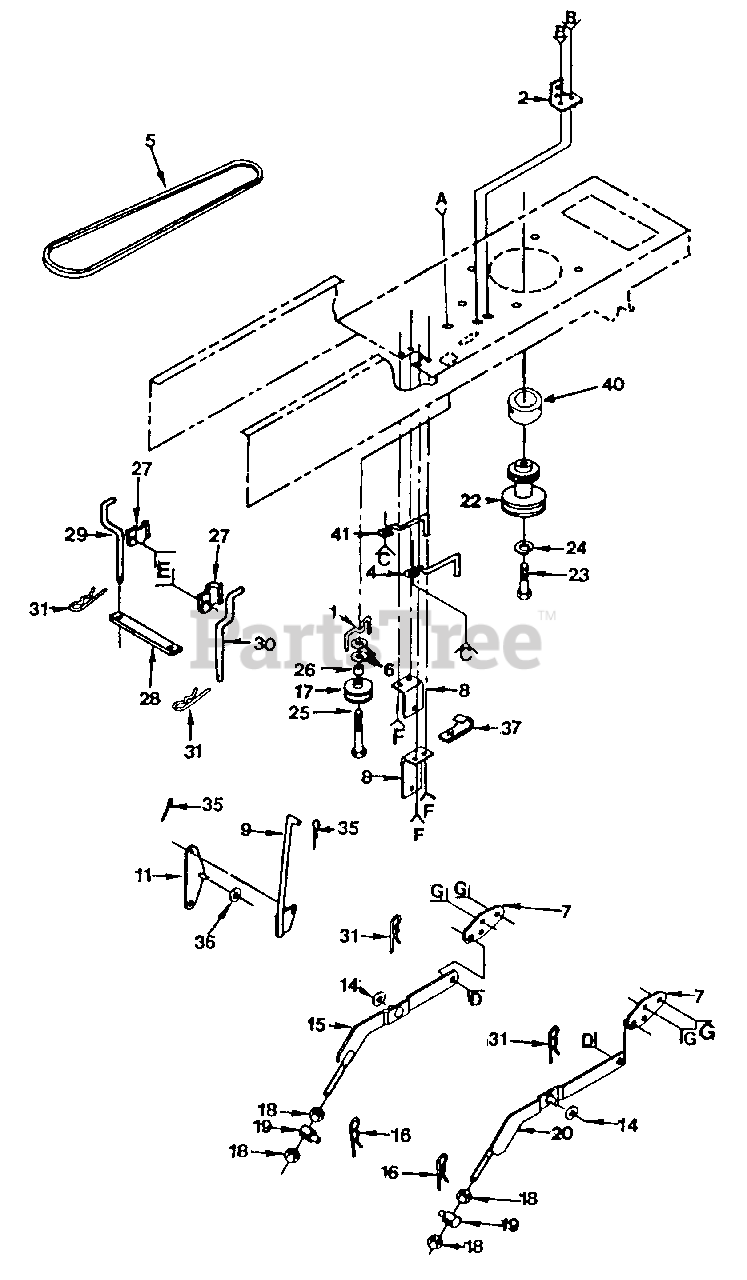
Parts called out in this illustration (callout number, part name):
1	Keeper, Belt
2	Bracket, Switch
5	V-Belt, Drive
6	Washer 13/32 x 13/16 x 12 Ga.
7	Bracket, Suspension
8	Bracket, Bellcrank
9	Rod Assembly, Clutch Primary
11	Bellcrank Assembly
14	Washer 17/32 x 15/16 x 16 Ga.
15	Arm Assembly, Suspension, L.H.
16	Retainer, Spring
17	Idler, Flat
18	Nut, Hex 1/2-13
19	Trunnion, Lift Lower
20	Arm Assembly, Suspension R.H.
22	Pulley, Engine
23	Bolt, Hex 7/16-20 x 1-3/4
24	Washer, Lock
25	Bolt, Hex 3/8-16 x 2-3/4
26	Spacer
28	Strap, Locator
29	Keeper, Belt, L.H.
30	Keeper, Belt, R.H.
31	Spring, Retainer
35	Pin, Cotter 1/8 x 3/4
36	Washer, 13/32 x 7/8 x 10 Ga.
37	Clip, Insulated
41	Keeper, Belt Engine
